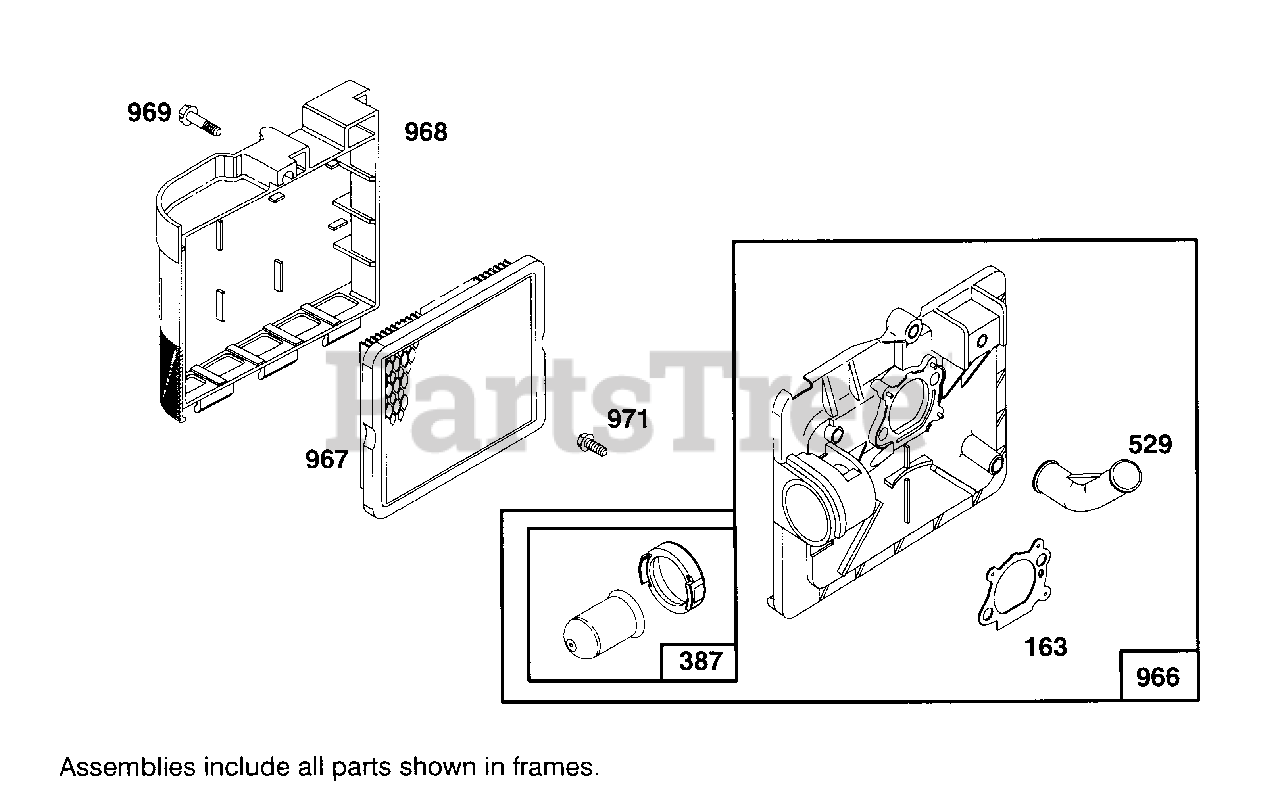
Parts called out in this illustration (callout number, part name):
163	Gasket-Air Cleaner
387	Primer-Carburetor
529	Grommet-Breather
966	Base-Air Cleaner
967	Filter-Air
968	Cover-Air Cleaner
969	Screw-Cover Mtg.
971	Screw-Air Cleaner
